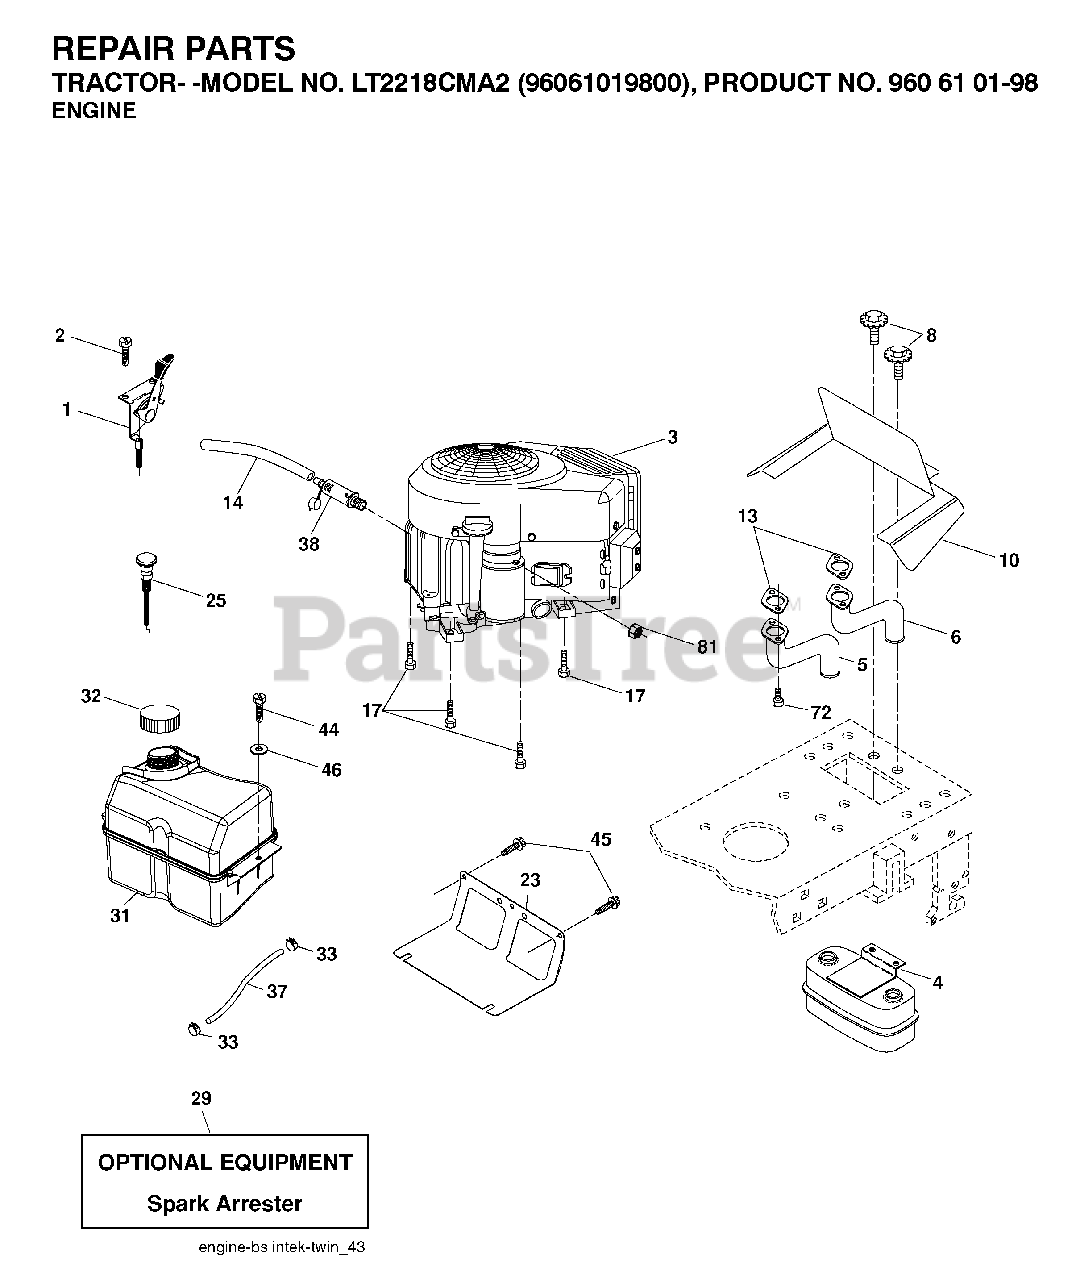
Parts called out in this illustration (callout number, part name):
1	THROTTLE CABLE
2	SCREW
4	MUFFLER.TWIN.CYL.LOW.TONE
5	EXHAUST TUBE RH
6	TUBE MANIFOLD LH
8	BOLT, 5/16-18 X 1 3/4
10	SHIELD.BROWNING.B&S
13	REPL BY 532 27 22-93
14	TUBE, DRAIN OIL ASM.
17	SCREW.3/8-16
23	SHEILD.BROWNING.DBR.GUARD
25	CONTROL CHOKE
29	ARRESTER SPARK (OPTIONAL)
31	TANK FUEL
32	FUEL CAP
33	HOSE CLAMP
37	LINE.FUEL.20
38	PLUG DRAIN OIL EASY
44	SCREW HEXWSHR 1/4-20X3/4
45	SCREW, 3/8-16X3/4
72	SCREW.SOCKET.HEAD.5/16-18
81	NUT
122	SCREW.1/4-20X5/8
123	SCREW, 5/16-18 X 1/2
